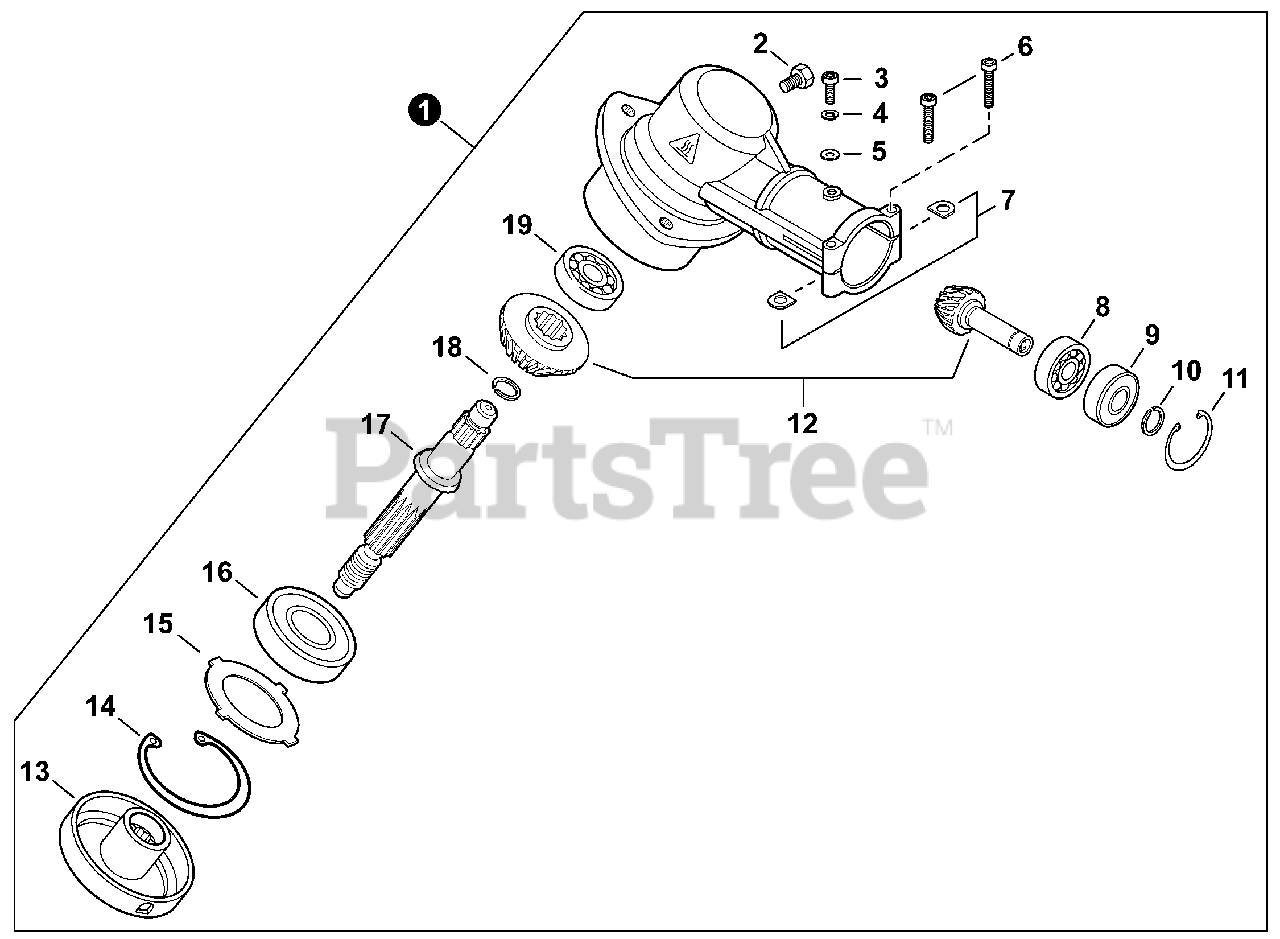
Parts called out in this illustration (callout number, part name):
1	GEAR CASE ASSY
2	BOLT M8×8
3	BOLT, TORX 5×10
4	WASHER, SPRING 5
5	WASHER, FLAT 5.5×10×0.8
6	BOLT, TORX 5×25
7	D-WASHER
8	BEARING, BALL 6900
9	BEARING, BALL 6900Z
10	RING, SNAP 10
11	RING, SNAP 22
12	GEAR SET
13	PLATE, ADAPTOR - UPPER
14	RING, SNAP 32
16	BEARING, BALL 6201
17	SHAFT, GEAR
18	RING, SNAP 12
19	BEARING, BALL 609
